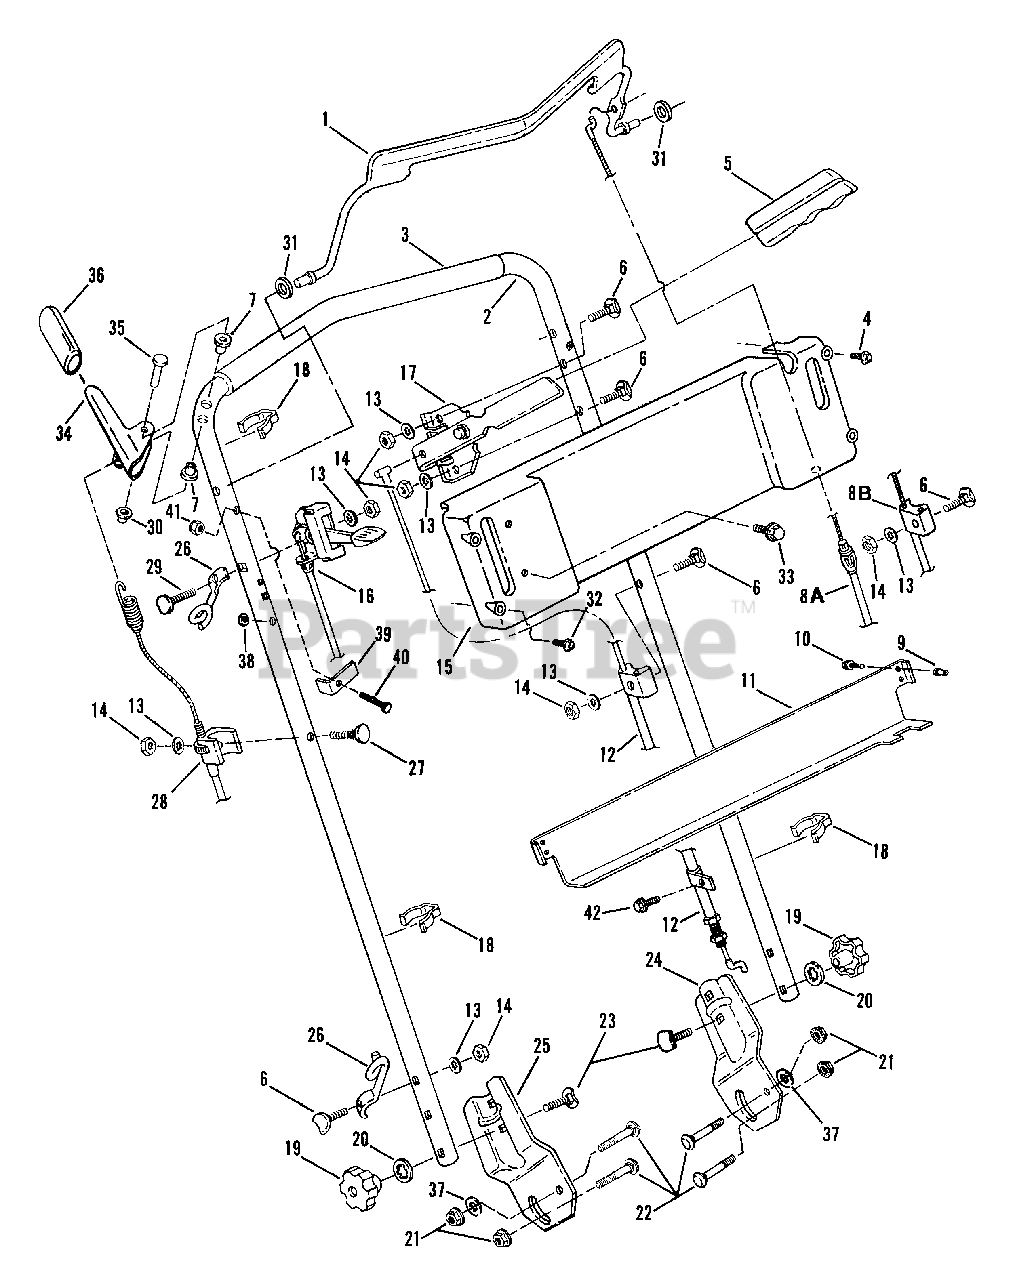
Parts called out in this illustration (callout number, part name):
1	CONTROL, Blade
2	HANDLE, Upper
3	GRIP, Upper Handle (Foam)
4	SCREW, #10-24 x 2" Self-Tapping
5	GRIP, Speed Selector
6	BOLT, 1/4-20 x 1-1/2" Curved Head Carriage
7	BUSHING
8A	CABLE, Blade Control
8B	CABLE, Blade Control
9	INSERT, Nylon
10	SCREW, #10-16 x 3/4" Self-Tapping
11	BRACE, Control Panel
12	CABLE, Speed Selector
13	WASHER, 1/4 Internal Tooth Lock
14	NUT, 1/4-20 Hex
15	PANEL, Console
16	CONTROL, Throttle
17	ASSEMBLY, Speed Selector Quadrant
18	CLIP, Cable
19	KNOB, 5/16-18 Internal Thread
20	WASHER, 5/16 Internal Tooth Lock
21	NUT, 5/16-18 Hex Flange Lock
22	BOLT, 5/16-18 x 1-1/4" Carriage
23	BOLT, 5/16-18 x 2" Curved Head Short Neck Carriage
24	BRACKET, Handle (Left Hand)
25	BRACKET, Handle (Right Hand)
26	GUIDE, Rope
27	BOLT, 1/4-20 x 1-7/8" Curved Head Carriage
28	ASSEMBLY, Clutch Cable
29	BOLT, 1/4-20 x 1-3/4" Curved Head
30	NUT, 1/4" Push
31	WASHER, 5/16 Flat
32	SCREW, #10-24 x 1-1/2" Self-Tapping
33	SCREW, #10-24 x 1/2" Hex Washer Self-Tap (Torx)
34	LEVER, Wheel Drive
35	PIN, 1/4 x 1-1/2" Clevis
36	GRIP, Wheel Drive Lever
37	WASHER, 5/16 Flat
38	SCREW, #10-24 x 1-1/2" Self-Tapping
39	BRACKET, Bail Stop
40	SCREW, #10-32 x 1-3/8" Hex Head Machine
41	NUT, #10-32 Hex Nyloc
42	SCREW, 1/4-24 x 5/8" Self-Tapping
